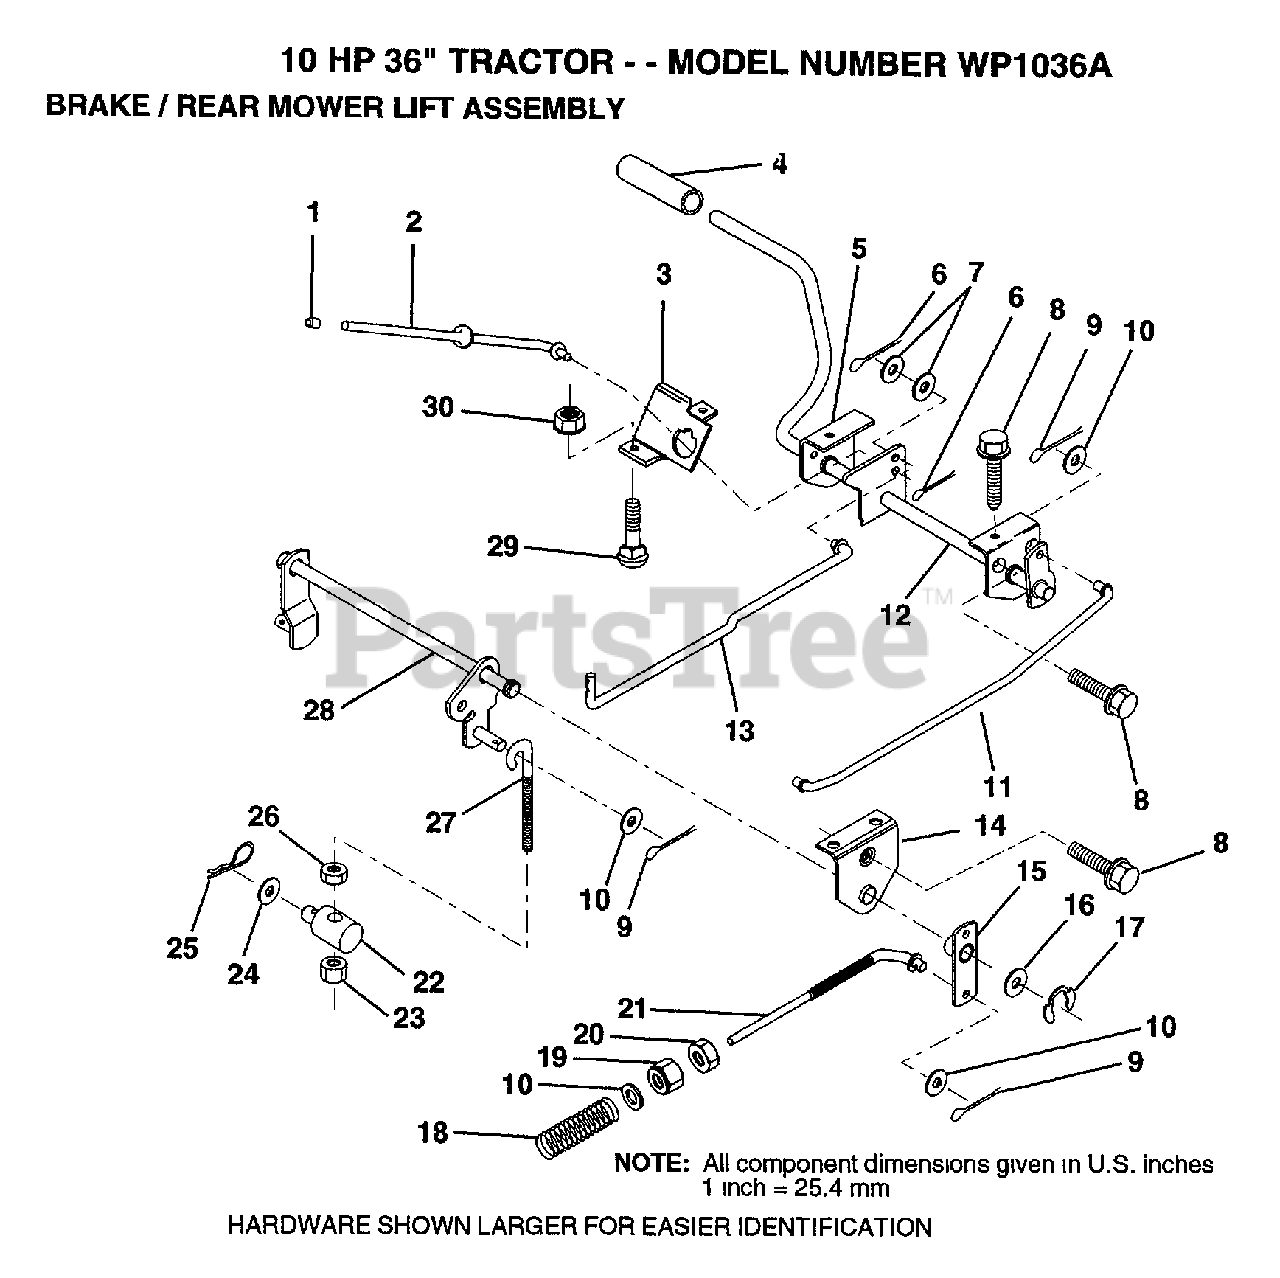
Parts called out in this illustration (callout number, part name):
1	PLUNGER CAP T
2	"ROD,PARK BRAKE"
3	"BRKT,PARK BRAKE"
4	FOOT PEDAL COVER
5	"BRKT,CLU PEDAL LH"
7	WASHER
8	SCREW LT
9	COTTER PIN
10	WASHER
11	"ROD,FRT BRAKE"
13	"ROD,CLUTCH"
14	"BRKT,LIFT SHAFT"
15	BRAKE PIVOT ARM
16	WASHER T
17	KLIP RING
18	SPRING ROD LT
20	NUT
24	WASHER
25	SPRING.RETAINER
26	LOCKNUT
27	"LINK, MOWER REAR"
